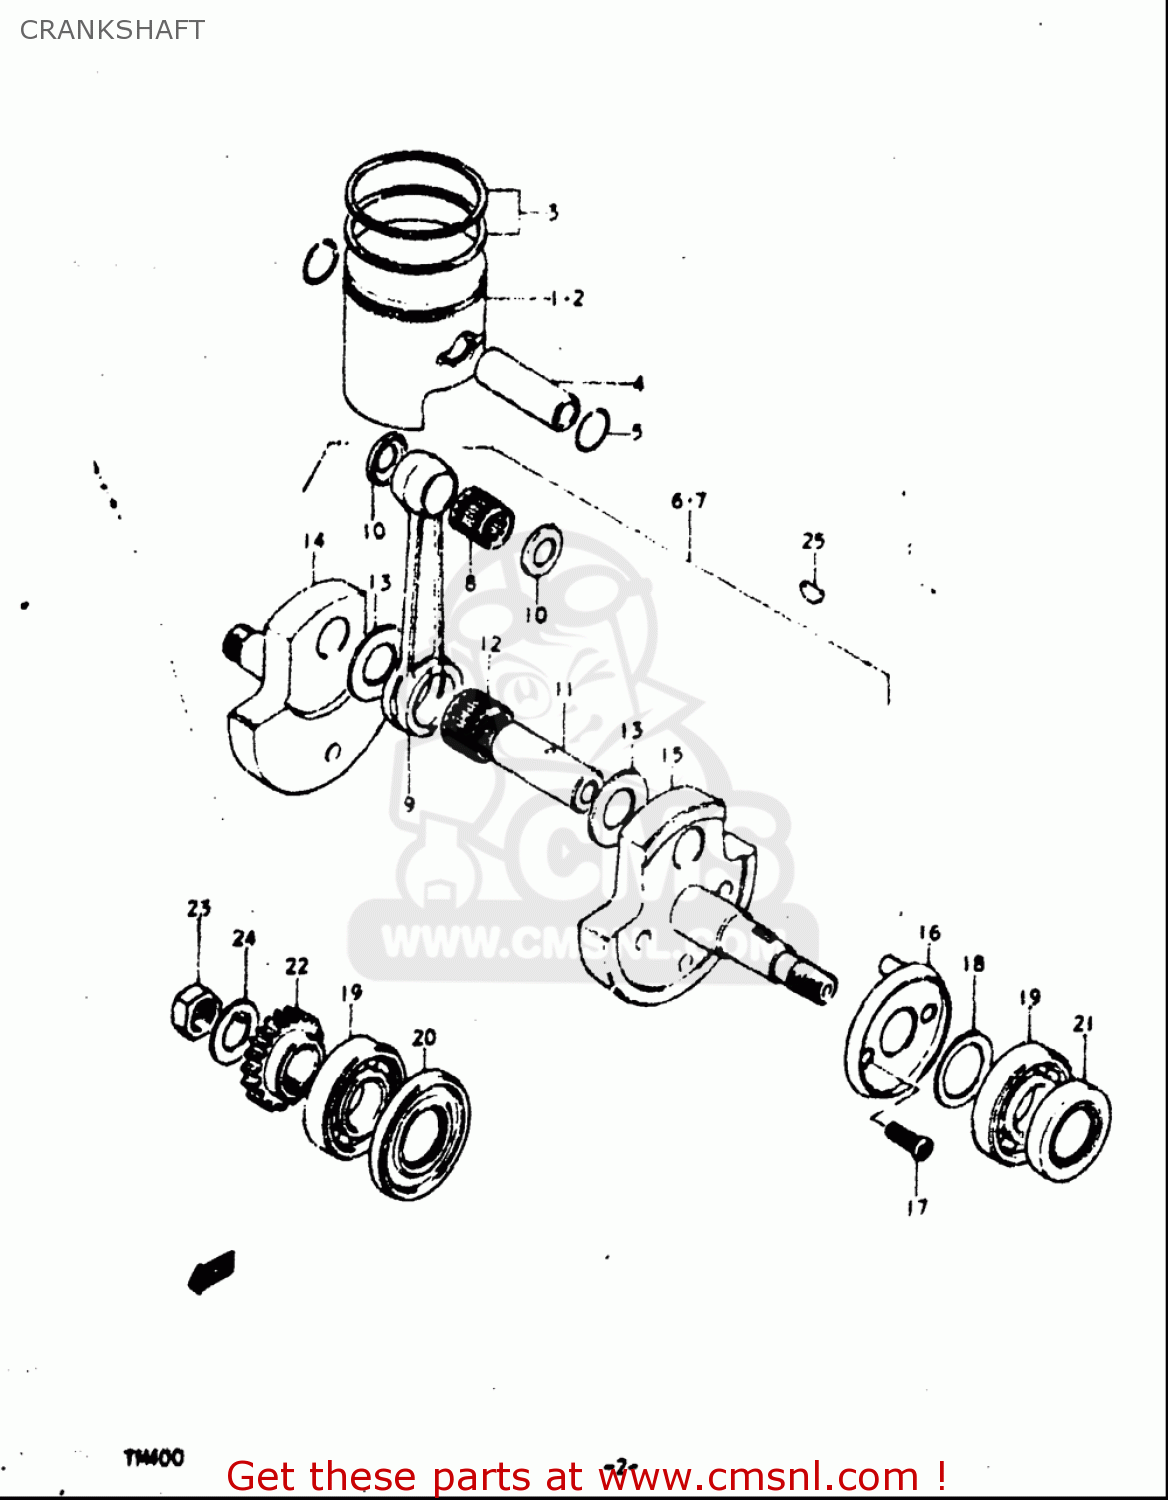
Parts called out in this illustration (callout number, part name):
1	PISTON (82.00MM)
4	PIN,PISTON
5	CIRCLIP,PISTON PIN
8	BEARING(20X25X27.9)
10	WASHER
11	PIN,CRANK
12	BEARING
13	WASHER(26X32X1.5)
17	SCREW
18	WASHER
19	BEARING(30X72X19)
20	SEAL,OIL(40X72X9)
21	OIL SEAL (30X55X10)
23	NUT (20MM)
25	KEY
